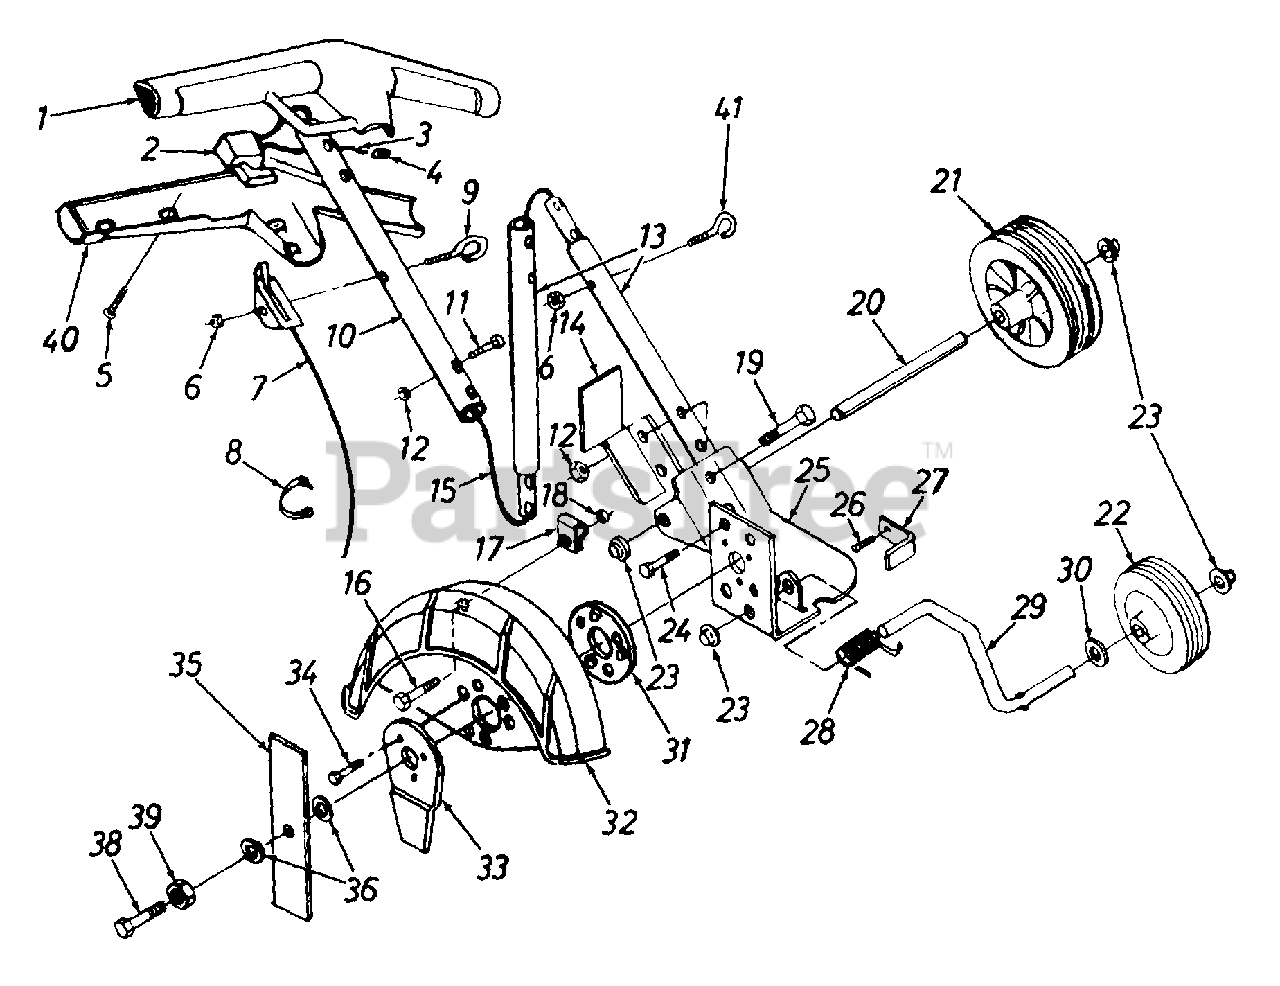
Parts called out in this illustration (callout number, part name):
1	Handle - Switch Housing (Upper)
2	Engine Switch
3	Ground Wire
4	Ground Clip
5	Pan Scr. #8 x .62"
6	Hex Lock Nut 1/4-20 Thd.
7	Choke Control Ass'y.
8	Cable Tie
9	Rope Guide Eyebolt
10	Upper Handle Tube
11	Hex Bolt #10-24 x 1.25" Lg.
12	Hex Ins. L-Nut #10-24 Thd.
13	Lower Handle Tube
14	Muffler Deflector Brkt.
15	Engine Wire Ass'y.
16	Hex Bolt 1/4-20 x .5" Lg.
17	Choke Clip
18	Hex L-Nut 1/4-20 Thd.
19	Hex Bolt #10-24 x 1.5" Lg.
20	Axle Pin
21	5" Wheel
22	4" Wheel
23	Push Nut
24	Hex Wash. Hd. Scr. 1/4-20 x .5" Lg.
25	Frame Base
26	Self-Tap Scr. #8-32 x .62"
27	Nose Wheel Stop Brkt.
28	Spring - Nose Wheel
29	Nose Wheel Axle
30	Fl-Wash. 3/8" I.D. x .875" O.D.
31	Spacer - Blade Guard
32	Blade Guard
33	Edge Guide
34	Self-Tap Scr. #10-32 x .75" Lg.
35	9" Blade
36	Bell-Wash. 3/8" I.D.
38	Hex Bolt 3/8-24 x 1.25" (Gr. 5)
39	Hex Nut 3/8-24 Thd.
40	Handle - Switch Housing (Lower)
41	Rope Guide Eyebolt
